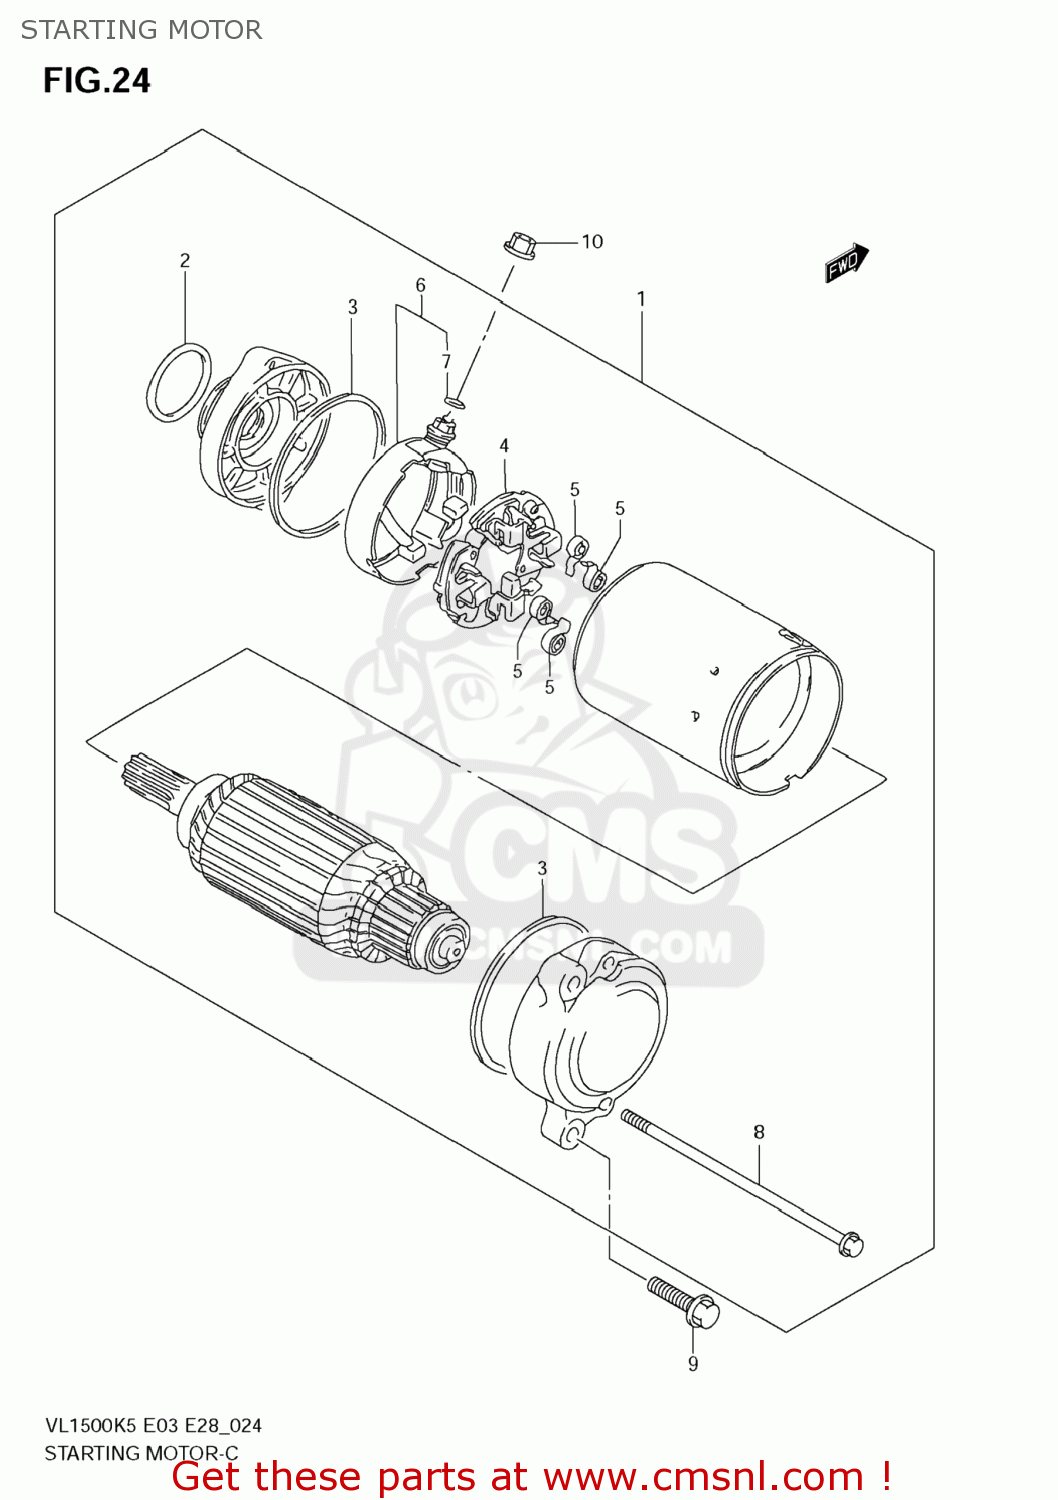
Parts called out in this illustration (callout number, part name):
1	MOTOR ASSY,STARTING
2	O-RING (D:2.1 ID:34.7)
3	O RING
4	HOLDER SET,BRUSH
5	SPRING,BRUSH
6	TERMINAL SET,BRUSH
7	O RING
8	BOLT
9	BOLT(6X25)
10	NUT
